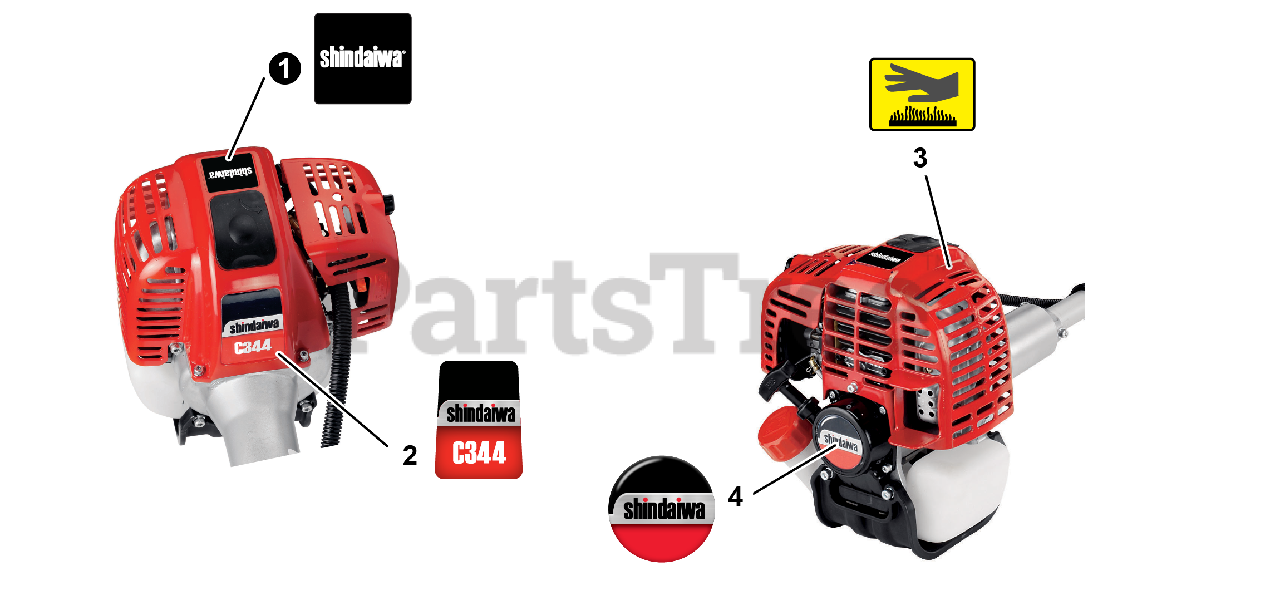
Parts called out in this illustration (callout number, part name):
1	LABEL, shindaiwa
2	LABEL - MODEL C344
3	LABEL, CAUTION - HOT
4	LABEL, RECOIL STARTER
